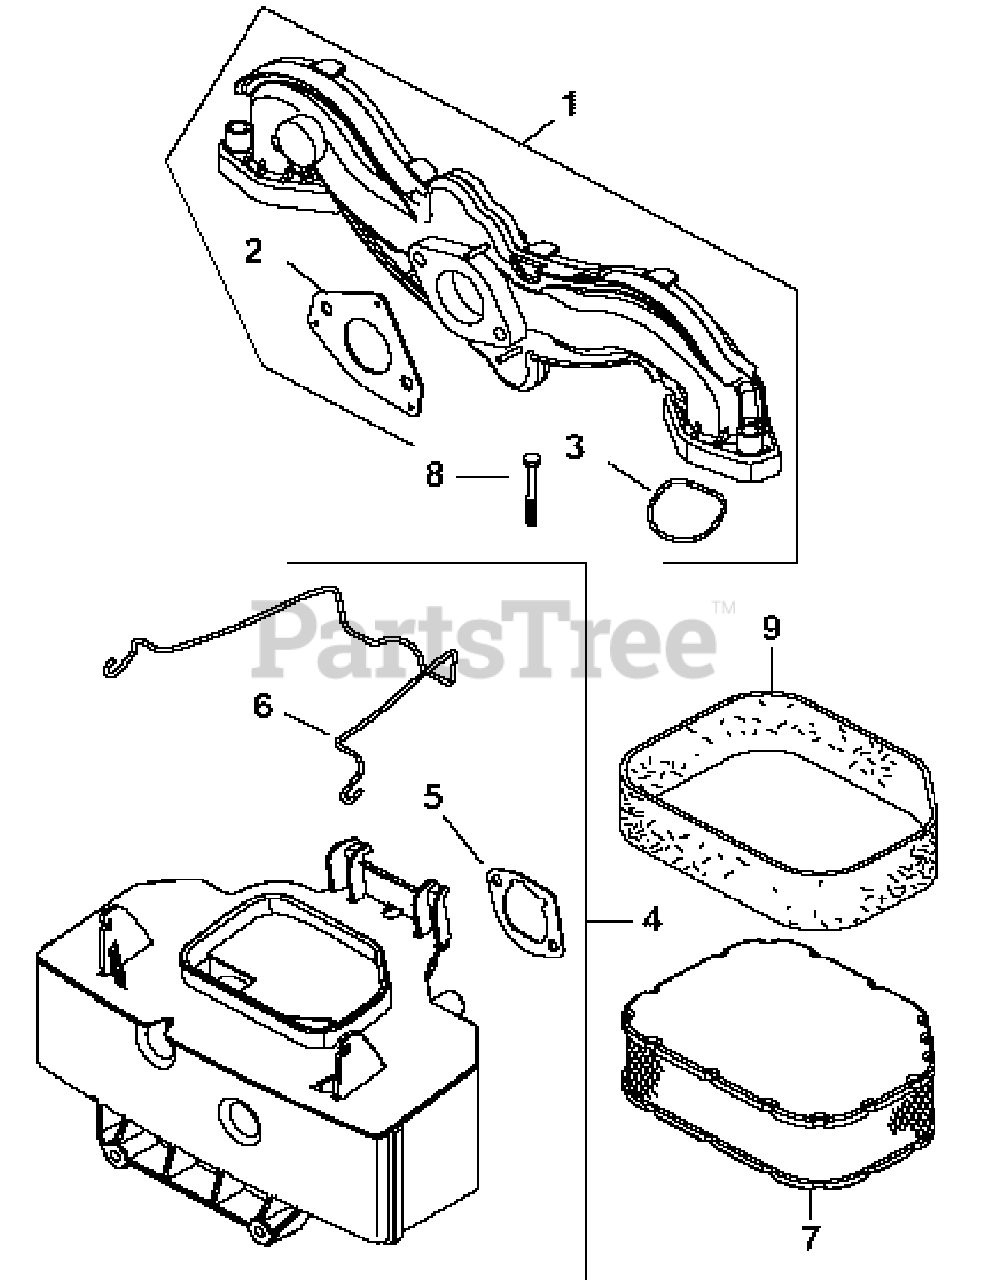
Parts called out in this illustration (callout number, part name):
1	Intake Manifold
2	CARBURETOR GASKET
3	Intake Port O-Ring
4	Air Cleaner Base
5	Air Cleaner Base Gasket
6	Air Cleaner Element Latch
7	Air Filter Element
8	Hex Flange Screw
9	Pre Filter
